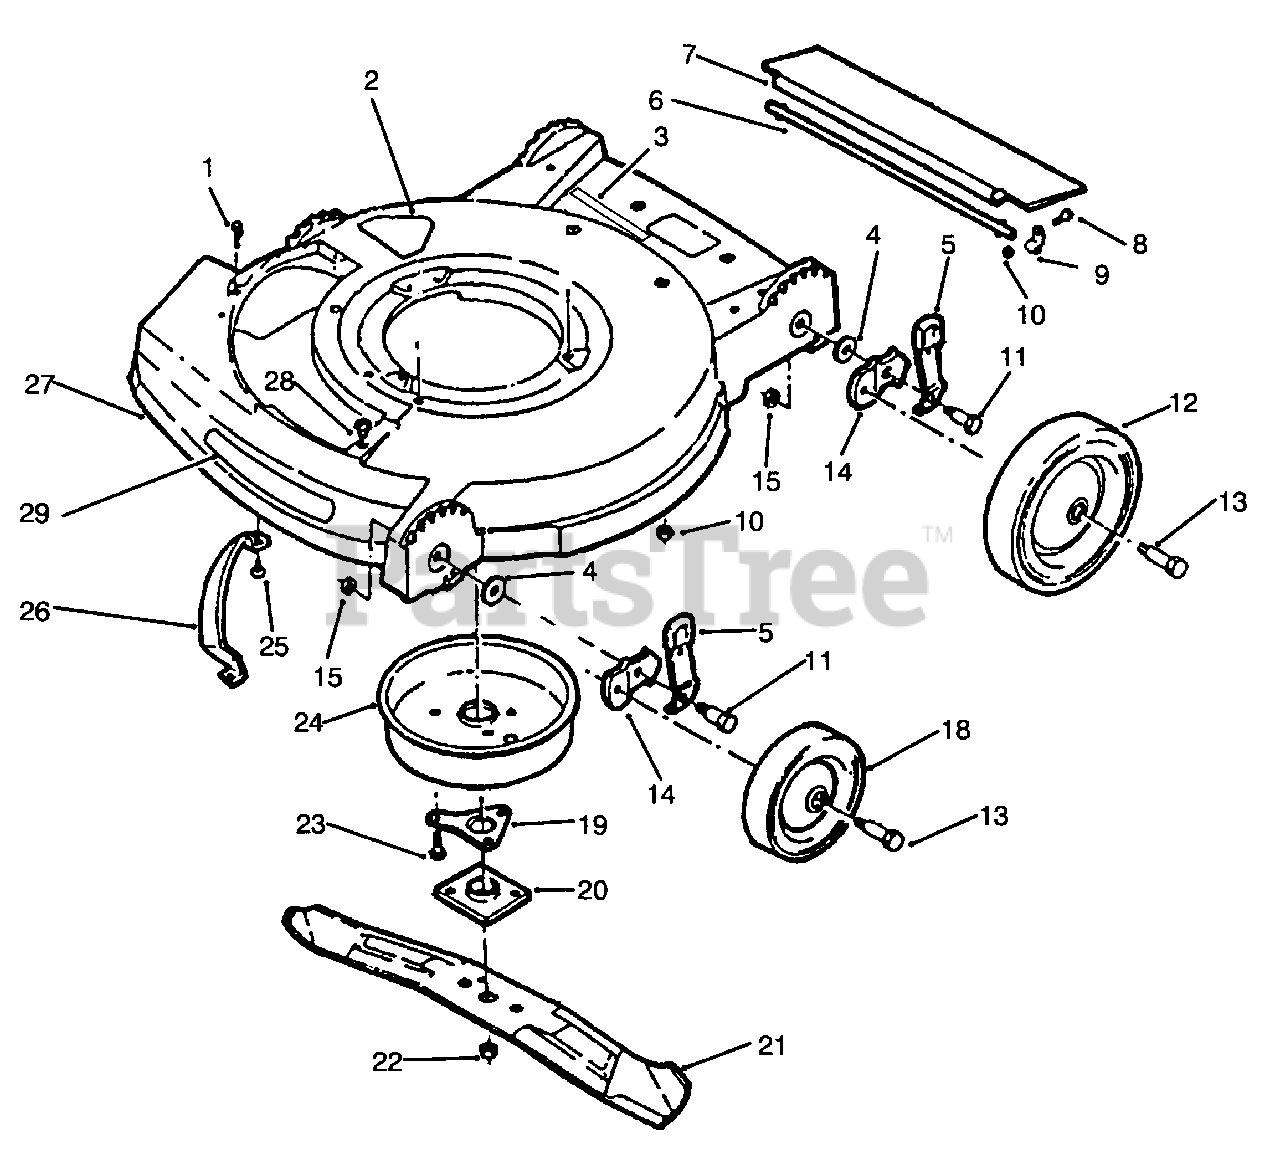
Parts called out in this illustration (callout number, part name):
1	Screw-Sems, Plate Cover
2	Decal-DIN
3	Decal-Danger
5	Knob & Spring-Adj.
6	Rod-Shield, Trailing
7	Shield-Trailing
9	Clamp-Rod, Shield
10	Nut-Lock
11	Bolt-Shoulder
12	Wheel-Rear, 8"
13	Bolt-Wheel
14	Bracket-Wheel Adj.
15	Nut-Lock
18	Wheel-Front, 6"
19	Plate-Support, Crankshaft
20	Collar & Plate
21	Blade-21"
22	Nut-Blade
23	Screw-Plate to Muffler Cover
24	Cover-Muffler
25	Screw-Toe Bar to Housing
26	Toe Bar
27	Assembly-Housing (Incl. Ref. 2 & 28)
28	Grommet
29	Decal-Deck 550C
